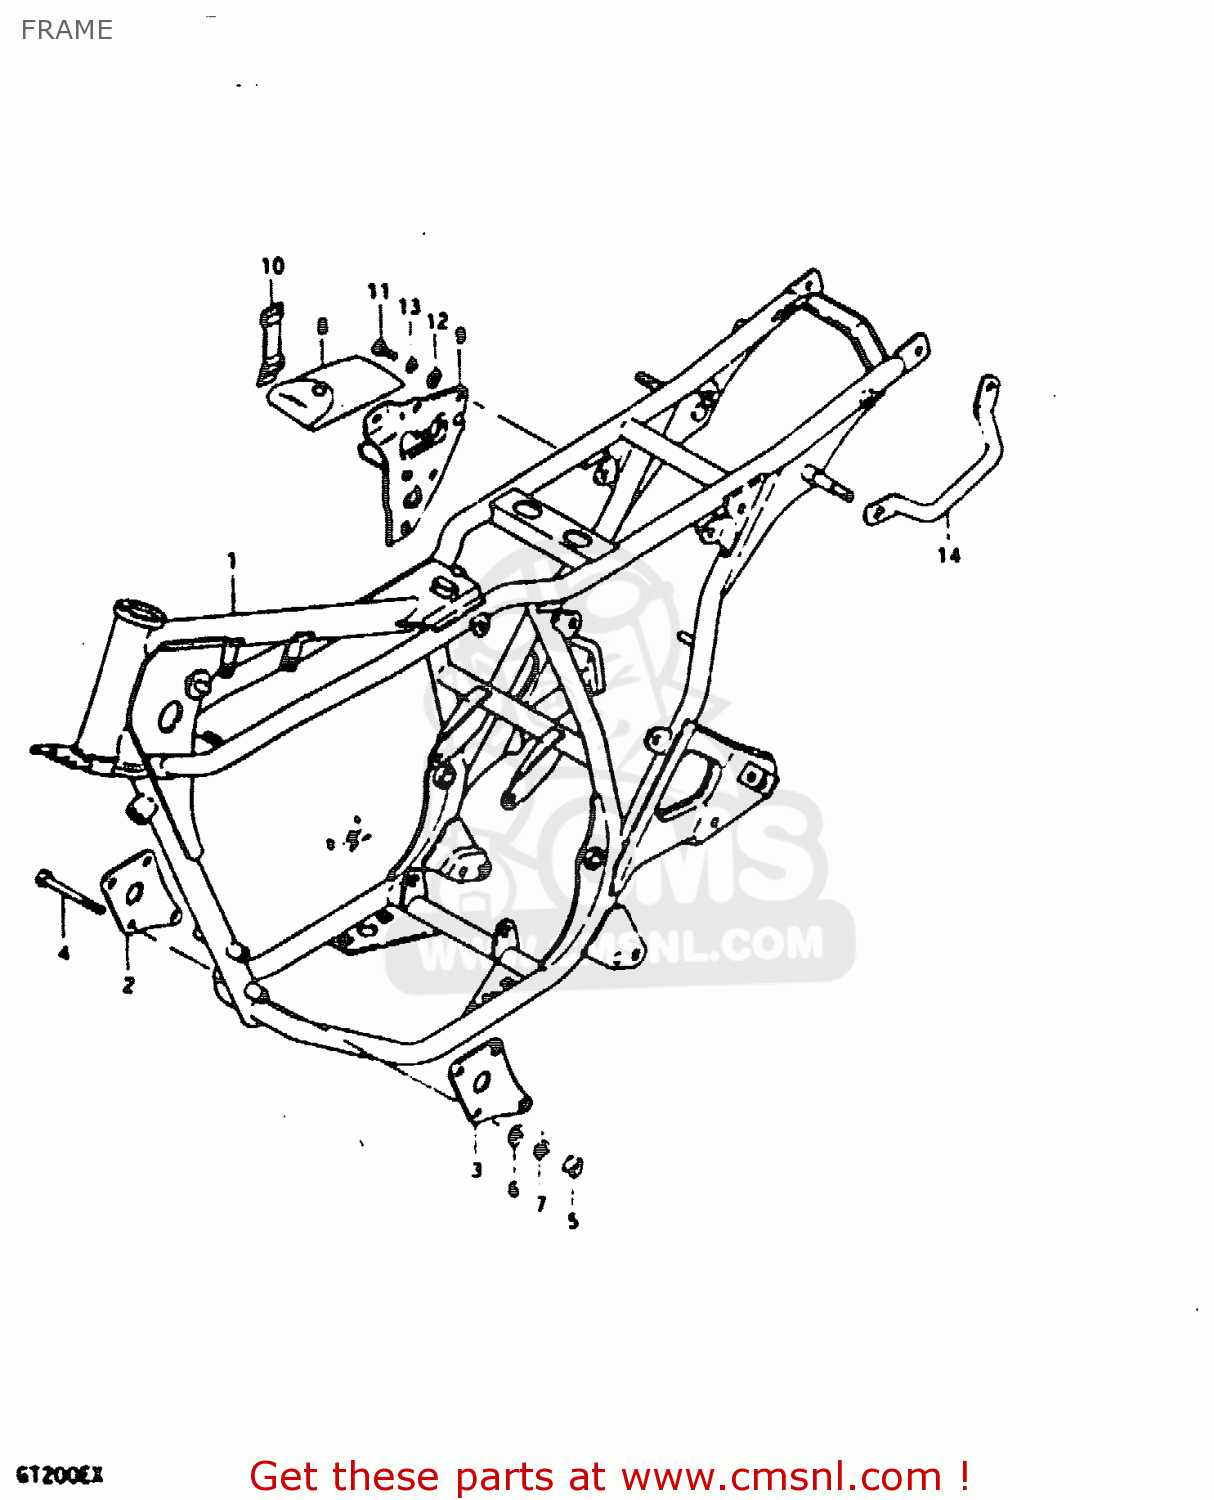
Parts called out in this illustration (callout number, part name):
1	FRAME
2	PLATE, ENGINE MOUNTING RH
3	PLATE, ENGINE MOUNTING LH
4	BOLT,8X75
5	NUT 8MM
6	WASHER
7	LOCK WASHER
8	TOOL SET
9	HOLDER, TOOL
10	BAND
11	BOLT
12	WASHER(6.5X16X1.2)
13	LOCK WASHER
14	GRIP, FRAME HANDLE
